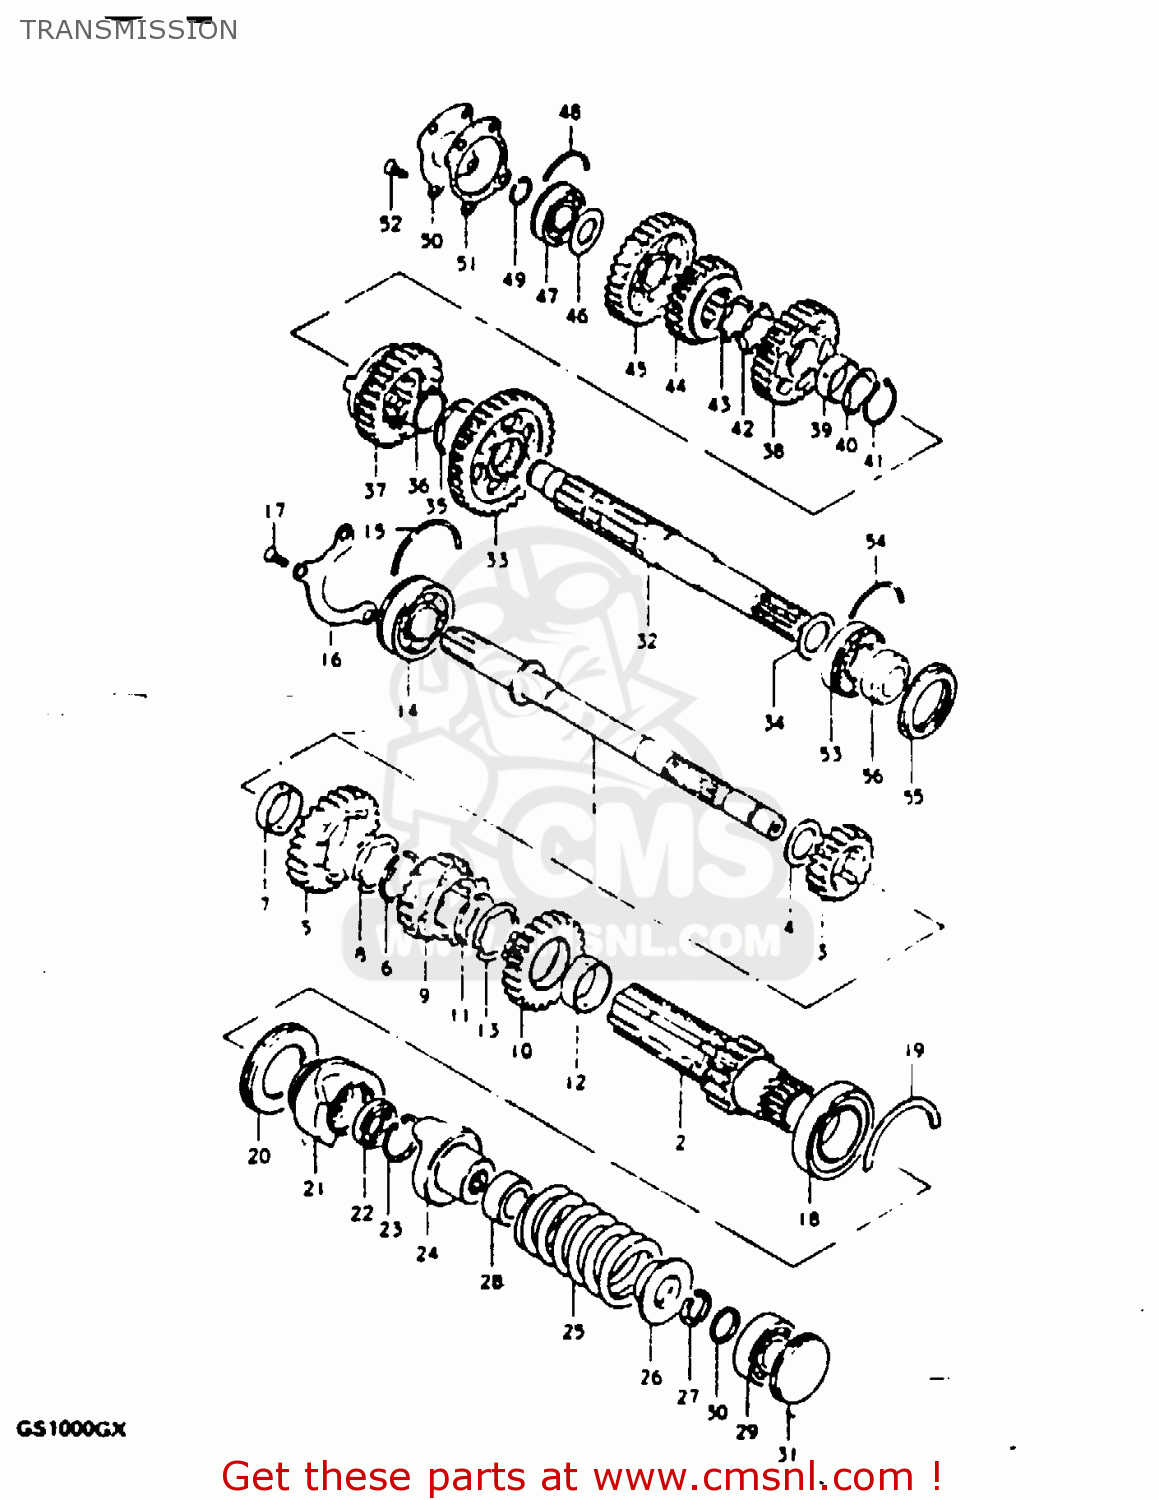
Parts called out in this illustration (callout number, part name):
1	SHAFT,COUNTER
2	SHAFT,OUTER COUNTER
3	GEAR,SECOND DRIVE
4	WASHER (21X35X2)
5	GEAR,5TH DRIVE(NT:26)
6	RING,SNAP
7	SPACER,DRIVE GEAR
8	LOCK WASHER,5TH DR GEAR SPACER
9	GEAR,THIRD DRIVE
10	GEAR,FOURTH DRIVE
11	RING,SNAP
12	SPACER,DRIVE GEAR
13	LOCK WASHER,5TH DR GEAR SPACER
14	BEARING(25X62X17)
15	C-RING
16	RETAINER,CNTR SHAFT BEARING
17	SCREW
18	BALL BEARING 32X58X13
19	C-RING
20	SEAL,OIL(40X58X7)
21	DOG,OUTPUT CAM
22	SEAL,OIL(20.6X31X6)
23	CIRCLIP
24	DOG,INPUT CAM
25	SPRING
26	STOPPER,CAM DOG
27	STOPPER,CAM DOG
28	GUIDE,CAM DOG SPRING
29	BEARING
30	SPACER (17X21X3.5)
31	PLUG
32	SHAFT,DRIVE
33	GEAR,FIRST DRIVEN
34	WASHER, LH
35	WASHER,LOCK
36	CIRCLIP
37	GEAR,FOURTH DRIVEN
38	GEAR,THIRD DRIVEN
39	BUSH,3RD DRIVEN GEAR
40	WASHER,LOCK
41	CIRCLIP
42	WASHER
43	WASHER,LOCK
44	GEAR,FIFTH DRIVEN
45	GEAR,SECOND DRIVEN
46	WASHER
47	BEARING(20X47X14)
48	C RING
49	CIRCLIP
50	PLATE,DRIVESHAFT
51	GASKET,DRIVESHAFT PLATE (MCA)
52	SCREW
53	BEARING
54	C RING
55	SEAL,OIL(35X52X6)
56	SPACER,DRIVESHAFT,LEFT
